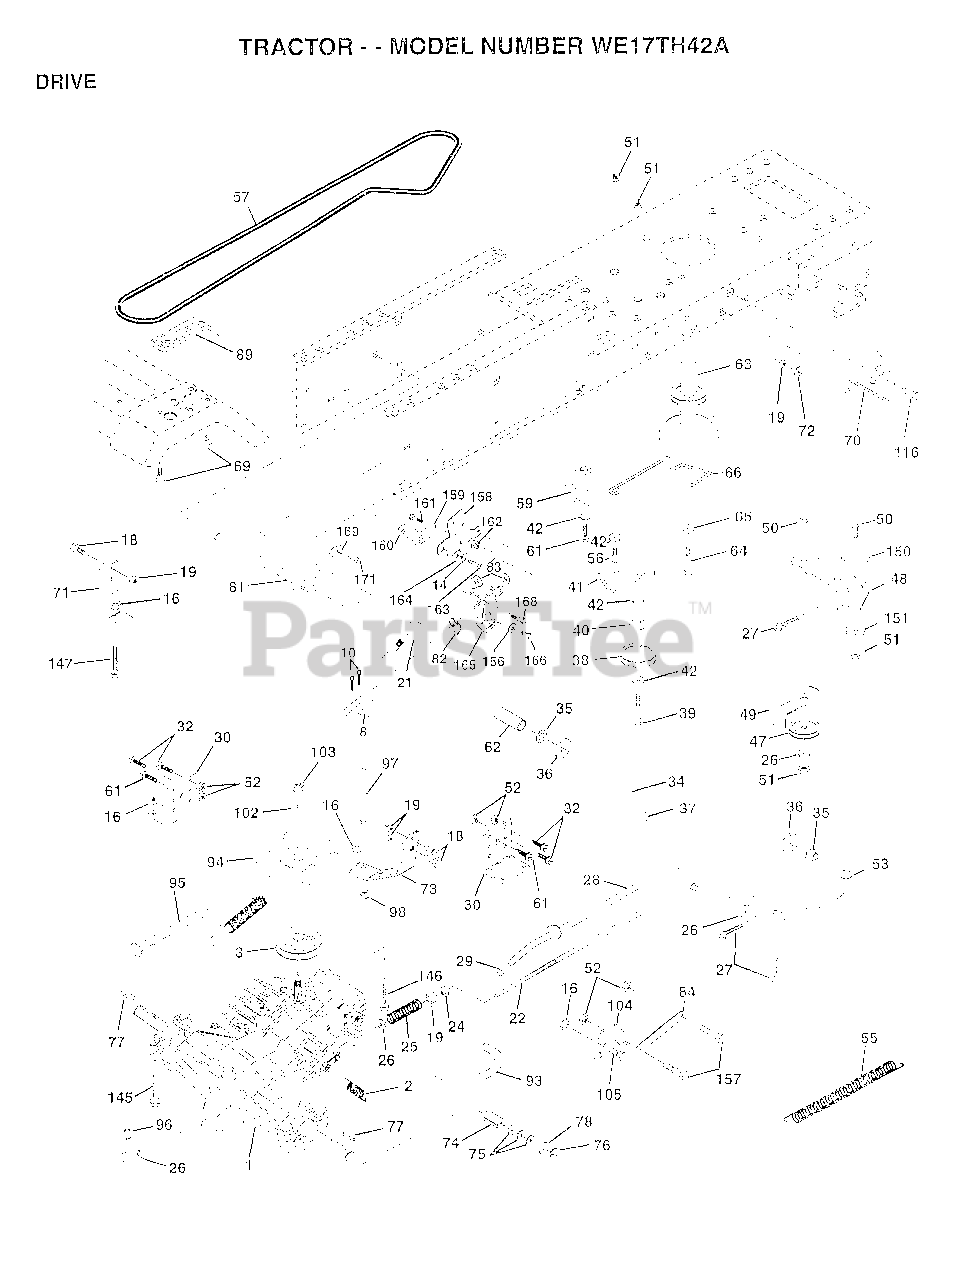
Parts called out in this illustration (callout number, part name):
2	SPRING RET BRAKE
3	PULLEY.TRANSAXLE
8	ROD.SHIFT.FENDER.ADJ.LT.CRD
10	PIN COTTER 1/8
14	LOCKWASHER
16	NUT
18	BOLT
19	NUT
21	KNOB T (1/2-HOLE)
22	ROD.BRAKE.HYDRO.
24	NUT
25	SPRING ROD LT
26	WASHER
27	COTTER PIN
28	ROD.BRAKE.PARK.LT
29	PLUNGER CAP T
30	TRANSAXLE MTG BKT
32	BOLT
34	SHAFT ASM-PEDAL F
35	NYLON BEARING
36	WASHER LT
38	FLAT IDLER PULLEY
39	BOLT
40	SPACER T
41	"KEEPER,BELT.IDLER FLAT"
42	WASHER
48	BELLCRANK.CLUTCH
49	RETAIN BELT
53	"LINK, CLUTCH T"
55	"SPRING, RETURN LT"
57	"BELT.GD DRV 82"""
59	KEEPER BELT CNTSP
61	SCREW
62	PEDAL COVER T
63	PULLEY.ENGINE
64	BOLT
65	LOCKWASHER
66	KEEPER-BELT
69	SCREW HEXWSH H-L
70	KEEPER BELT ENG
71	STRAP TORQ LH HYD
72	WASHER
73	"STRAP-TORQUE,RH"
74	SPACER SPLIT
75	WASHER
76	E-RING LT
77	SQUARE KEY
78	WASHER
81	SHAFT.ASM.CROSS
82	"SPRING,TORSION"
83	WASHER
84	LINK.TRANSAXLE.LT/YT
89	CONSOLE.SHIFT.LT
93	"LINE FUEL HYD 4"""
94	"FAN 7"" HYDRO"
95	CONTROL.ASM.BYPASS.HYDRO.99
96	RETAINER M
97	BOLT KEEPER RH
98	NUT
102	WASHER BELLEVILLE
104	ARM CONTROL HYDRO
105	SCREW CAP 5/16-18
116	BOLT RDHD 3/8-16
145	BOLT.HEX.FLGHD
146	BOLT.HEX.FLGHD.
147	BOLT.HEX.FLGHD
150	BUSHING.BELLCRANK.GRD.DR
151	WASHER
156	WASHER.SRRTD.5/16
157	"BOLT,SHOULDER"
158	BRKT.SHIFT.MOUNT
159	HUB.SHIFT
160	WASHER
161	BOLT T
164	WASHER.5/8X.281X10GA
165	BRKT.PIVOT.LEVER
166	SCREW.5/16-18X5/8
168	BOLT.SHOULDER.5/16-18X.561
169	PLATE.FASTENING
171	SCREW LT
